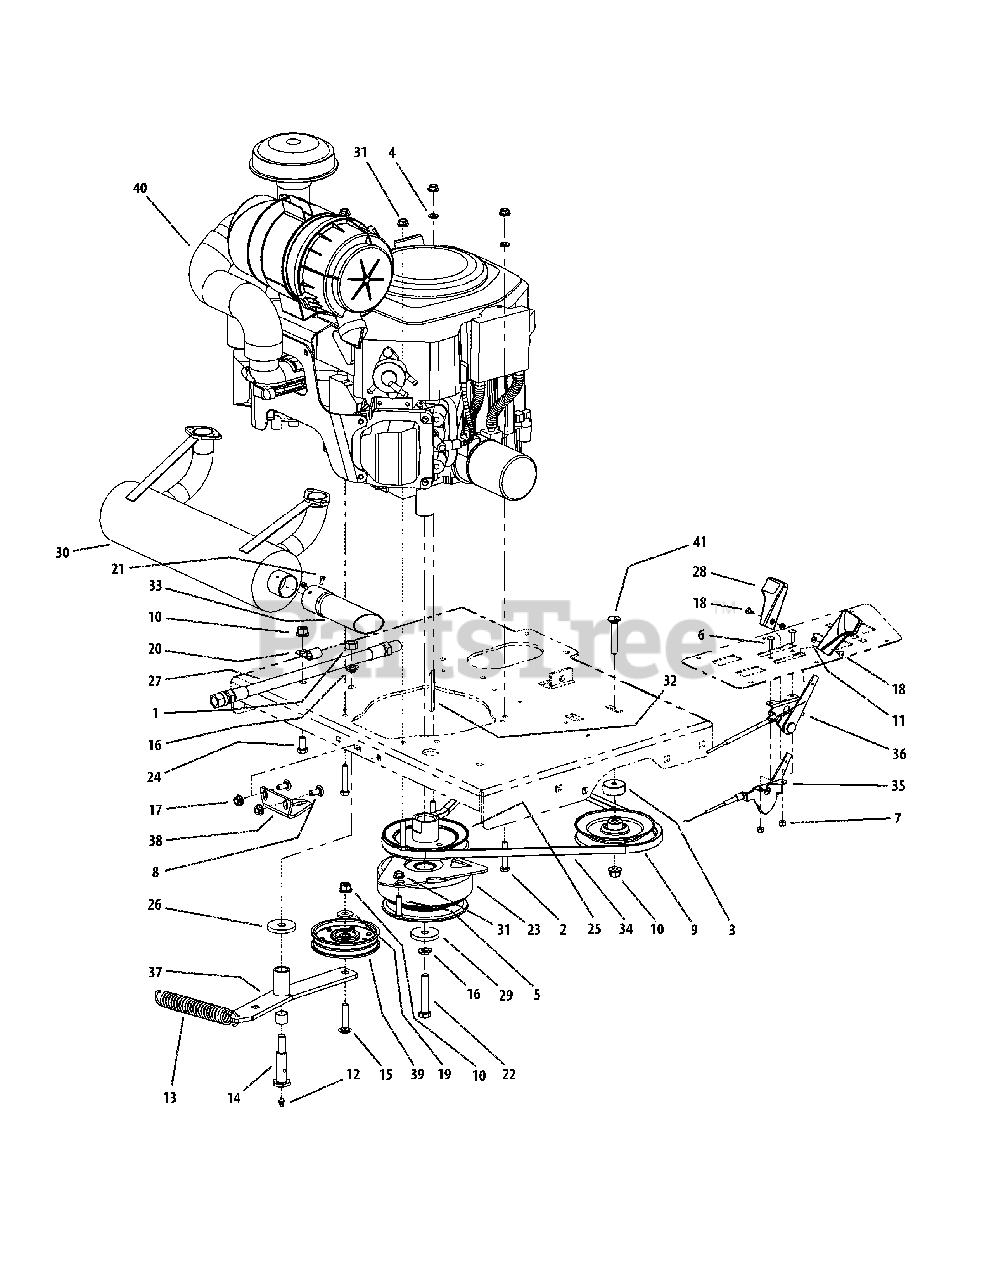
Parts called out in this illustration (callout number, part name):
1	Hex Nut, 7/16-14
2	HHCS, 5/16-18, 1-3/4
3	Spacer, .385 ID x 1.500 OD x 0.585
4	Flat Washer, .320 ID x .591 OD x .078
5	HHCS, 5/16-18 x 1-1/4
6	Machine Screw, 10-32 x 5/8
7	Lock Nut, Nylon Insert, 10-32
8	Carriage Bolt, 5/16-18 x .75
9	Idler Pulley
10	Flange Lock, Hex Nut, 3/8-16
11	Nut Washer, W/Star, 8-32
12	Grease Fitting, 1/4-28 x 3/16
13	Spring Extension, 1.0 OD x 5.00S
14	Shoulder Screw, 7/16-14
15	Hex Carriage Screw, 3/8-16, 1.75
16	Lock Washer, 7/16
17	Hexflange Lock Nut, 5/16-18
18	Machine Screw, 8-32, .375
19	Flat Washer, .406 ID, 1.0 OD, .105
20	Clip, Heat Shield Cable
21	Screw, #10-16 x 0.500
22	Capscrew, 7/16-20 x 2.50
23	Clutch Brake, 1.125 ID
24	Hex Cap Screw, 3/8-16, .750
25	Pump Drive Pulley
26	Flat Washer, 7/16 ID x 1.75 OD x .25
27	Oil Drain Hose
28	Control Throttle Knob
29	Flat Washer, 7/16 ID x 1.75 OD x .25
30	Muffler Accessory Kohler
31	Nut, 5/16-18, Flangelock
32	Key, 1/4 x 1/4 x 2.75
33	Exhaust Pipe
34	Belt, 50.125 Lg
35	Throttle, Control Cable
36	Choke, Control Cable
37	Engine Idler Arm Assembly Includes:
37	Bearing
38	Retainer Clutch Assembly
39	Flat Pulley with Flanges
40	Engine, 23HP Kohler
40	Engine, 25HP Kolher
41	Carriage Bolt, 3/8-16 x 2.25
